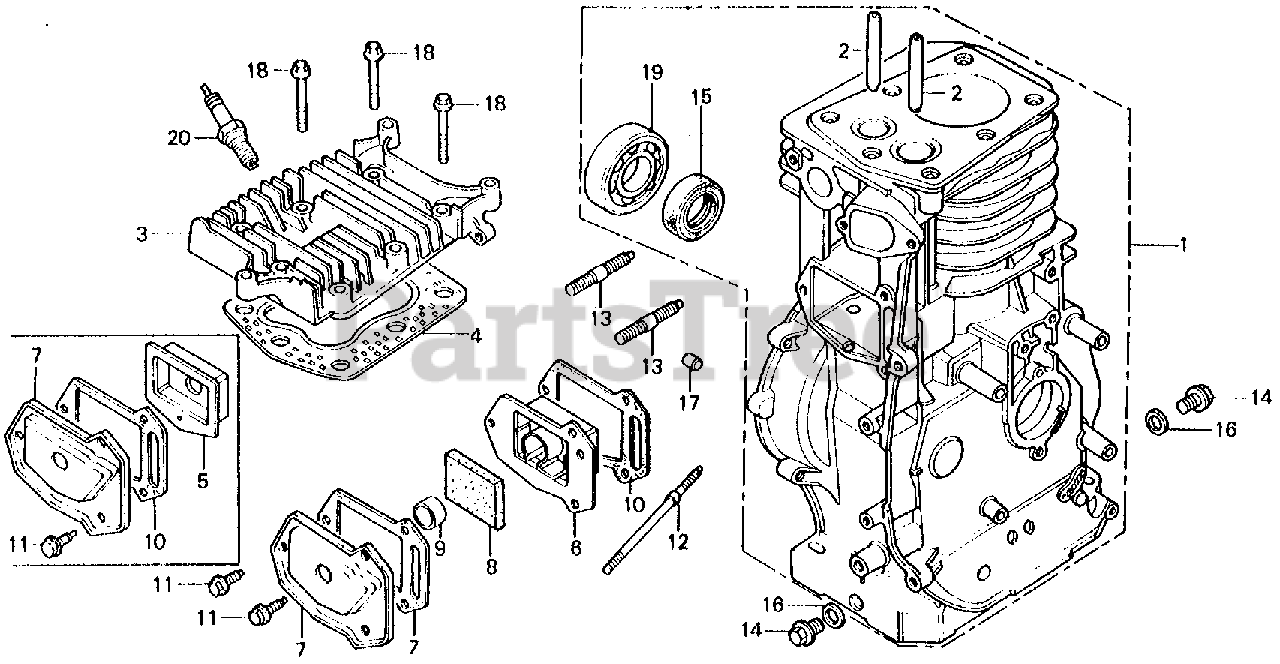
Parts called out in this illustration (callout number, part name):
1	CYLINDER ASSY.
2	GUIDE, VALVE (OS)
3	CYLINDER HEAD
4	GASKET, CYLINDER HEAD
5	CASE, BREATHER
6	CASE, BREATHER
7	COVER, TAPPET ROOM
8	FILTER, BREATHER
9	SEAL, BREATHER
10	GASKET, TAPPET COVER
11	BOLT, FLANGE (6X12) (CT200)
12	BOLT, STUD (6X96)
12	BOLT, STUD (6X89)
13	BOLT, STUD (8X35)
14	BOLT, DRAIN PLUG
15	OIL SEAL (25X41X6)
16	WASHER, DRAIN PLUG (12MM)
17	PIN A, DOWEL (8X14)
18	BOLT, FLANGE (8X45)
19	BEARING, RADIAL BALL (6205)
20	SPARK PLUG (BR-4HS) (NGK)
20	SPARK PLUG (W14FR-U) (DENSO)
